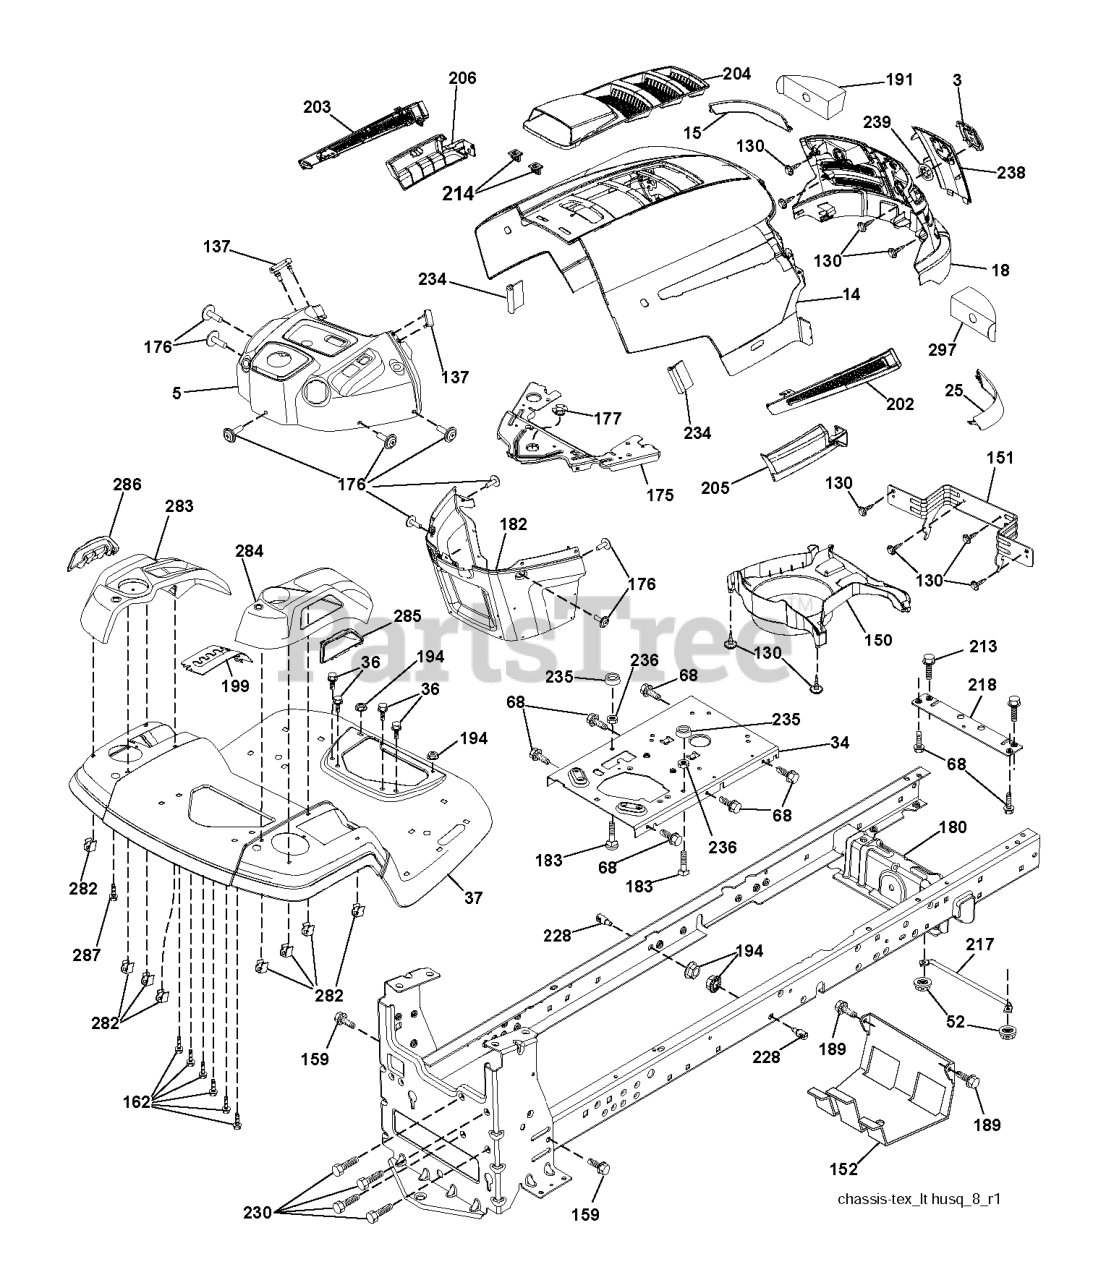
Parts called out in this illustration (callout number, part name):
3	RP LOGO
5	DASH
14	HOOD
15	LENS.HUSQVARNA LT.LH
18	RP GRILLE/LENS ASM.
25	LENS.HUSQVARNA LT.RH
34	PLATE.ENGINE.WELDED.CHASSIS
36	SCREW 5/16"
37	RP FENDER.TLT.FS.W/CPH.422
52	LOCKNUT
68	Screw 5/16-18 x 1/2 Hex, Self Tapping 5/16-18 x 1/2
130	SCREW.#10 X 0.750.BOS
137	BUMPER DASH
151	BRACKET PIVOT
152	SHIELD.BROWNING.W/TEX
159	SCREW, 3/8-16X3/4
162	SCREW.HI-LO.CONSOLE
175	CROSSMEMBER
176	SCREW.#10-24X5/8.RN.QU
177	BUSHING STEERING
180	CHASSIS
182	DASH.LOWER.PREDATOR LT
183	BOLT.5/16-18X1-1/4 FULL.THREAD
189	SCREW
191	INSERT REFLECTIVE
194	NUT LOCK HEX FLANGE 5/16-18
199	PLATE.DECK.LIFT.HUSQ.LT
202	VENT SIDE HOOD RH
203	VENT SIDE HOOD LH
204	VENT TOP HOOD
205	SKIRT SIDE RH
206	SKIRT SIDE LH
213	BOLT
214	CLIP.RETAINER.TINNER.
217	ROD.PIVOT.HOOD
218	X-PIECE.HOOD.STOP.NON/
228	STUD.FASTNER.W/ANTI-ROTATE
230	SHOULDER BOLT 5/16-18TT
234	BUMPER.HOOD.TEX.HUSQVARNA
235	SPACER FENDER
236	NUT.CENTERLOCK.5/16-
238	TRIM
282	CLIP.RETAINER.CONSOLE.LT.HUSQ
283	CONSOLE.DECK.LIFT.HUSQ.N/FR.GR
284	CONSOLE.CNTRL.
285	CONSOLE INSERT RH
286	CONSOLE.INSRT.LH.HUSQ.LT.BLACK
287	SCREW 1/4X20
297	INSERT.REFLECTIVE.RH.
